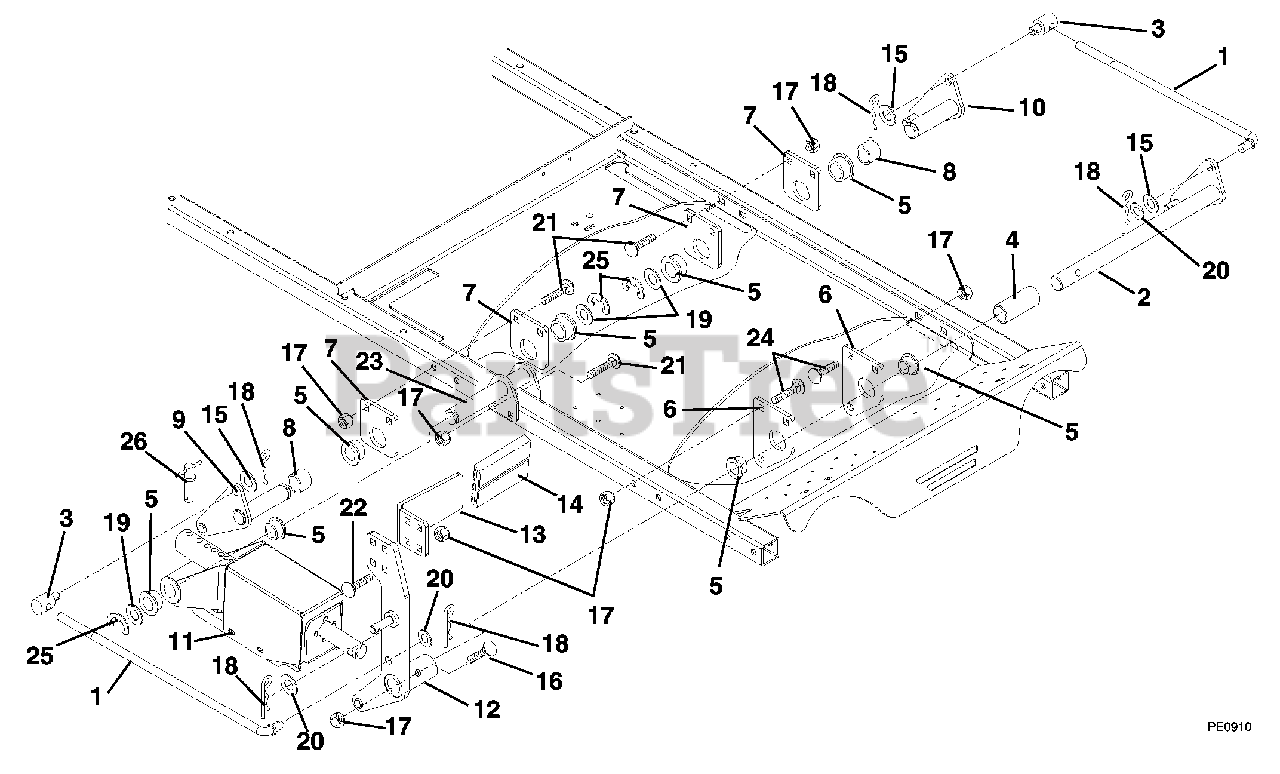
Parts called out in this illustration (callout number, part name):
1	Linkage, Lift
2	Weldment, Lift, Front
3	Trunnion
4	Bushing, Front
5	Bushing, Flange 1.02 x 1.385 x .75 x 1.75 Nylon
6	Bracket, Mount, Front
7	Bracket, Mount, Rear
8	Bushing, Rear
9	Weldment, Lift, Rear Right Hand
10	Weldment, Lift, Rear Left Hand
11	Assembly, Zoom Lift
12	Weldment, Lift Pedal Mount
13	Pedal, Foot Lift
14	Pad,Pedal
15	Washer, Flat Steel .511 x 1.44 x .125
16	Bolt, Hex .38-16 x 2.00 Grade 5
17	Nut, Locking Top Flange .38-16
18	Pin, Hair External
19	Washer, Flat Steel 1.06 x 2.00 x .134
20	Washer, Flat Steel .531 x 1.06 x .095
21	Bolt, Round Head Square Neck .38-16 x 2.50 Grade
22	Bolt, Round Head Square Neck .38-16 x 1.00 Grade 5
23	Weldment, Pivot Mount
24	Bolt, Round Head Square Neck .38-16 x 2.25 Grade 5
25	Ring, Retaining .82 x 1.50 x .05
26	Pin, Spring Ball .375 O.D. x 1.50
